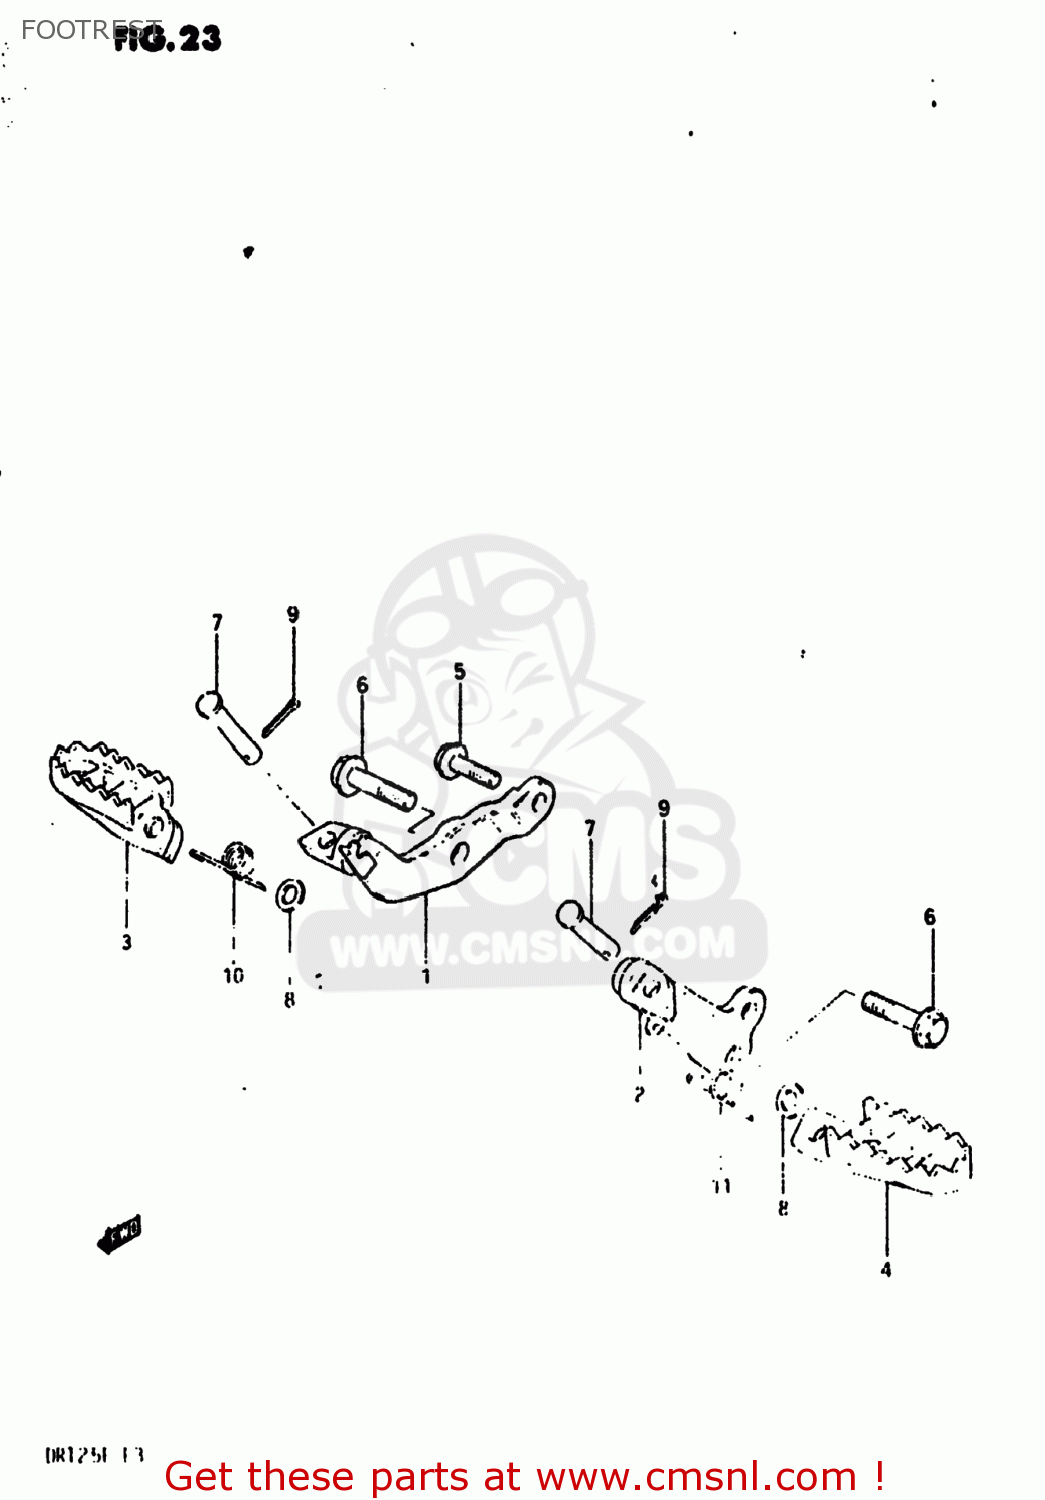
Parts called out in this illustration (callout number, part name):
1	BAR,FRONT FOOTREST
2	BAR,FRONT FOOTREST,LEFT
3	FOOTREST,RIGHT
4	FOOTREST
5	BOLT
6	BOLT
7	PIN
8	WASHER
9	PIN 20X20
10	SPRING
11	SPRING,FOOTREST,LEFT
